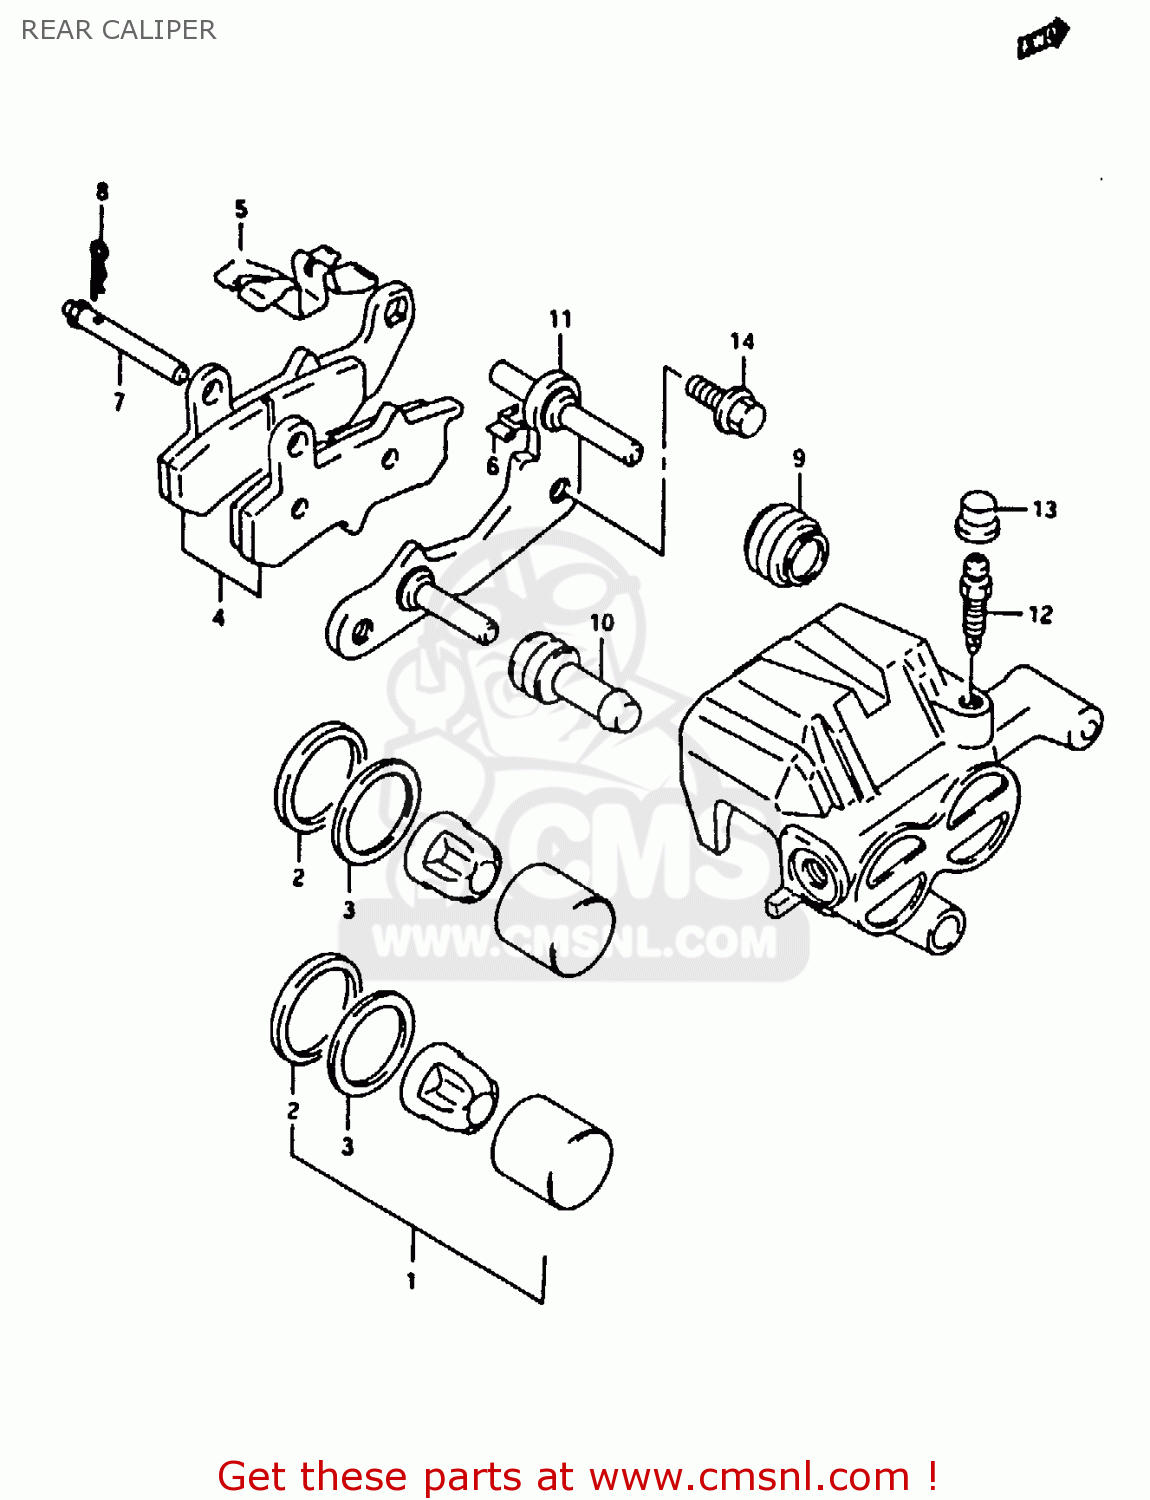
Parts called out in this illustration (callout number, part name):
1	BRAKE PISTON SET
2	SEAL,PISTON
3	SEAL,WIPER
4	PAD SET (NAS)
5	SPRING,PAD
6	GUIDE,PAD
7	PIN,PAD
8	CLIP,PAD PIN
9	BOOT,AXLE
10	INSULATOR,AXLE
11	CARRIER
12	BLEEDER
13	CAP,BREATHER
14	BOLT
